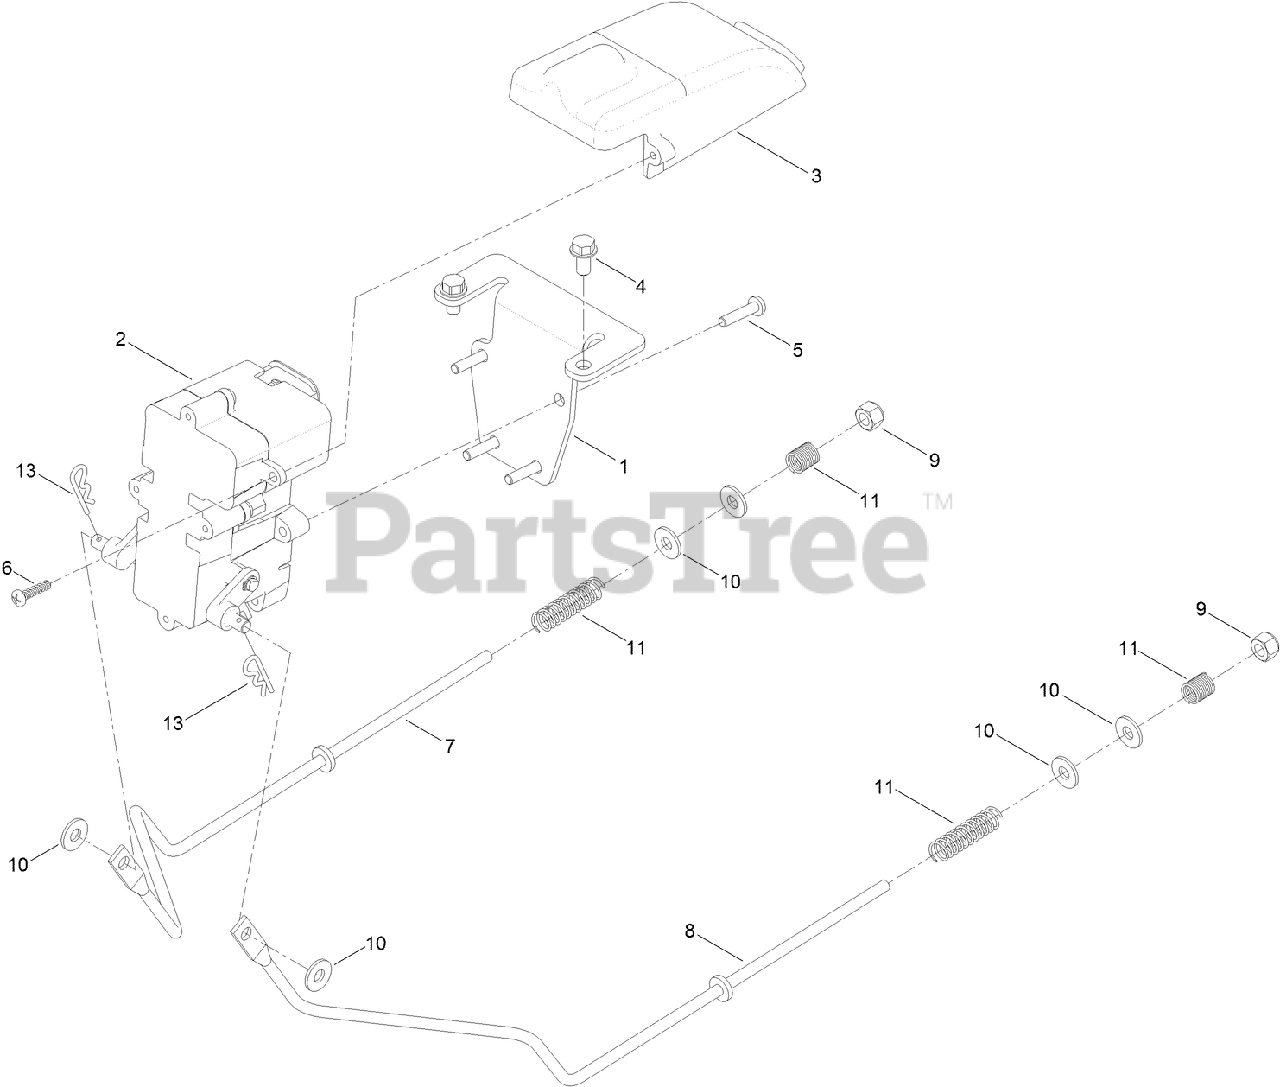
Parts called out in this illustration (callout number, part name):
1	BRACKET-MOUNT, BRAKE
2	BRAKE BOX ASM
3	COVER-CONNECTOR
4	SCREW-HWH
5	SCREW-PPH
6	SCREW-PPH
7	ROD-BRAKE, WIDE (RH)
8	ROD-BRAKE, WIDE (LH)
9	NUT-LOCK, NI
10	WASHER
11	SPRING-COMPRESSION
